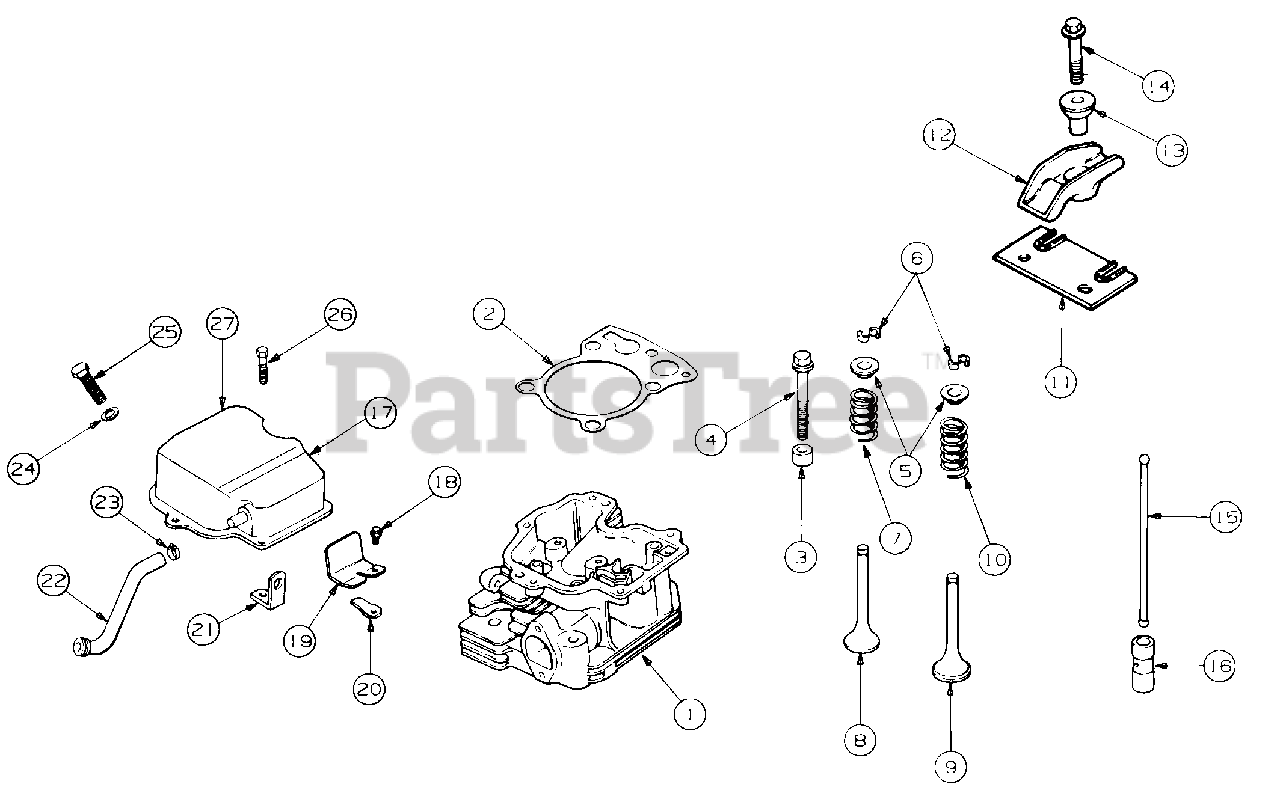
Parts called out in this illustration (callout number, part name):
1	Cylinder Head
2	Gasket, Cylinder Head
3	Spacer, Head Bolt Exhaust Port
4	Screw, Cylinder Head M10 x 1.5 x 81
5	Cap, Valve Spring
6	Kit, Retainer
7	Spring, Exhaust Valve
8	Valve, Exhaust, Std
9	Valve, Intake, Std
10	Spring, Intake Valve
11	Plate, Guide
13	Ball, Pivot Rocker
14	Screw, Pivot Rocker M6 x 1.0 x 34
15	Rod,Push
16	Lifter, Valve
17	Cover, Valve w/Nipple
18	Screw, Breather Reed Ret, M5 x 0.8 x 10
19	Retainer, Breather Reed
20	Reed, Breather
21	Strap, Lifting
22	Hose, Breather
23	Clamp, Hose
24	Washer, Flat
25	Screw, Valve Cover M6 x 1.0 x 25
26	Screw, Valve Cover M6 x 1.0 x 20
27	Graphic, OHV Engine
